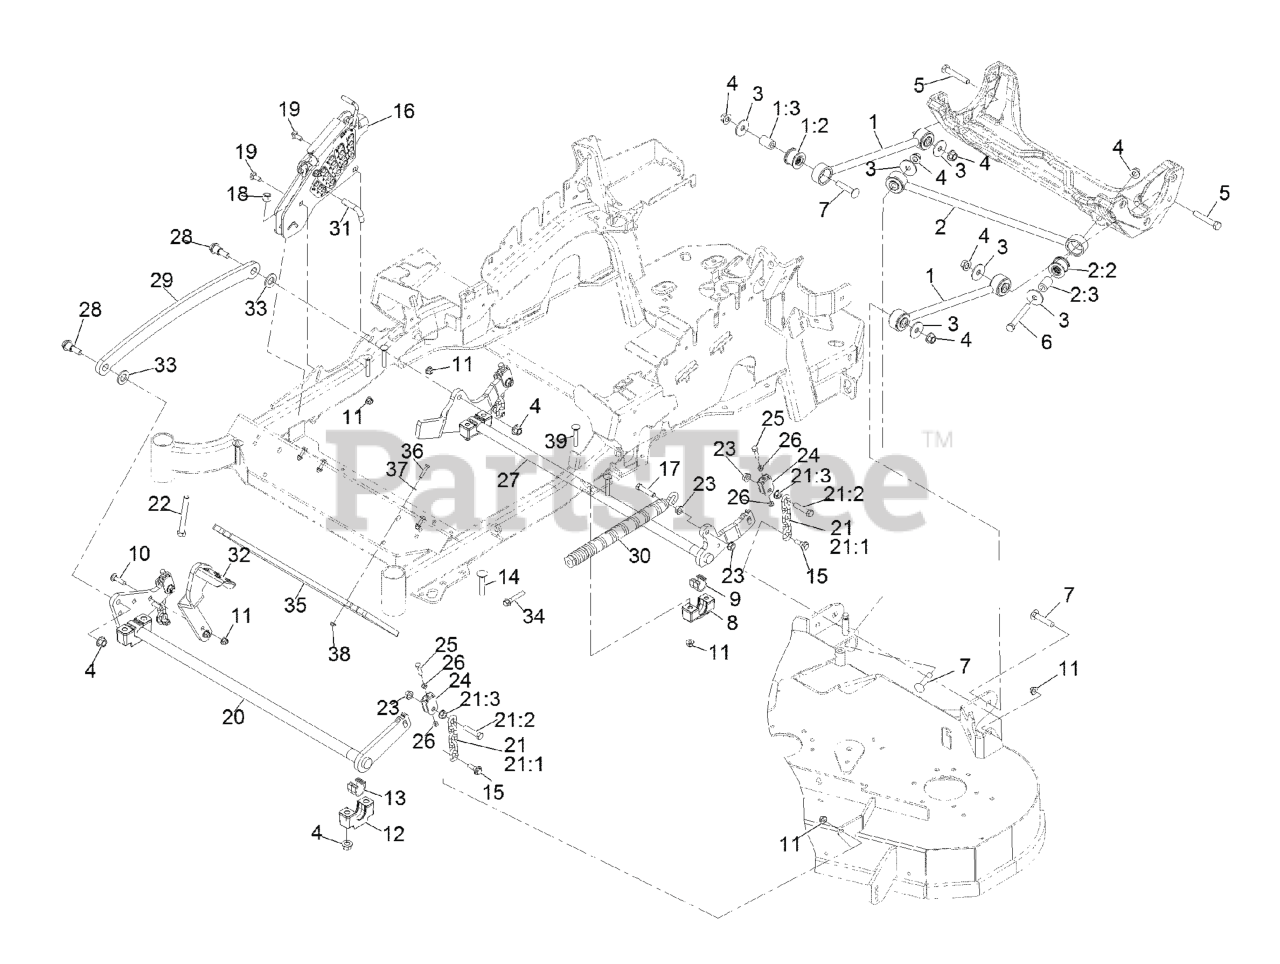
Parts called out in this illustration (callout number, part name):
1	LONG STRUT ASM
1:2	BUSHING-SUSPENSION, RUBBER
3	PANHARD ROD ASM
3:2	BUSHING-SUSPENSION, RUBBER
4	WASHER-THRUST
5	Nut-Lock 1/2-13
6	SCREW-HH
7	SCREW-HH
8	SCREW-CARR
9	SUPPORT-CROSS SHAFT, BEARING REAR
10	BEARING-CROSS SHAFT, REAR
11	SCREW-CARR
12	NUT-HF, NI
13	SUPPORT-CROSS SHAFT, BEARING
14	BEARING-CROSS SHAFT, FRON
15	Bolt-Carriage 1/2-13 X 2 1/2 Spl Neck
16	SCREW-SHOULDER, HHF
17	HOC ASM
18	SCREW-HH
19	NUT-LOCK, NI
20	BOLT-CARR
21	DECKLIFT-FRONT
22	DECK LIFT CHAIN ASM
22:1	CHAIN-LIFT, DECK
22:2	SCREW-HH
23	BOLT-TAP
25	YOKE-ADJUST, DECK
26	SCREW-HH
27	NUT-JAM
28	LIFT-DECK, REAR
29	SCREW-SHOULDER, HHF 1/2-13 X 1.12
30	LINK-LIFT, DECK
31	SPRING-EXTENSION
32	PIN-HOC
33	LEVER-FOOT
34	WASHER-FLAT
35	BOLT-SHOULDER
36	Bolt-Carriage 3/8-16 X 2 1/4
